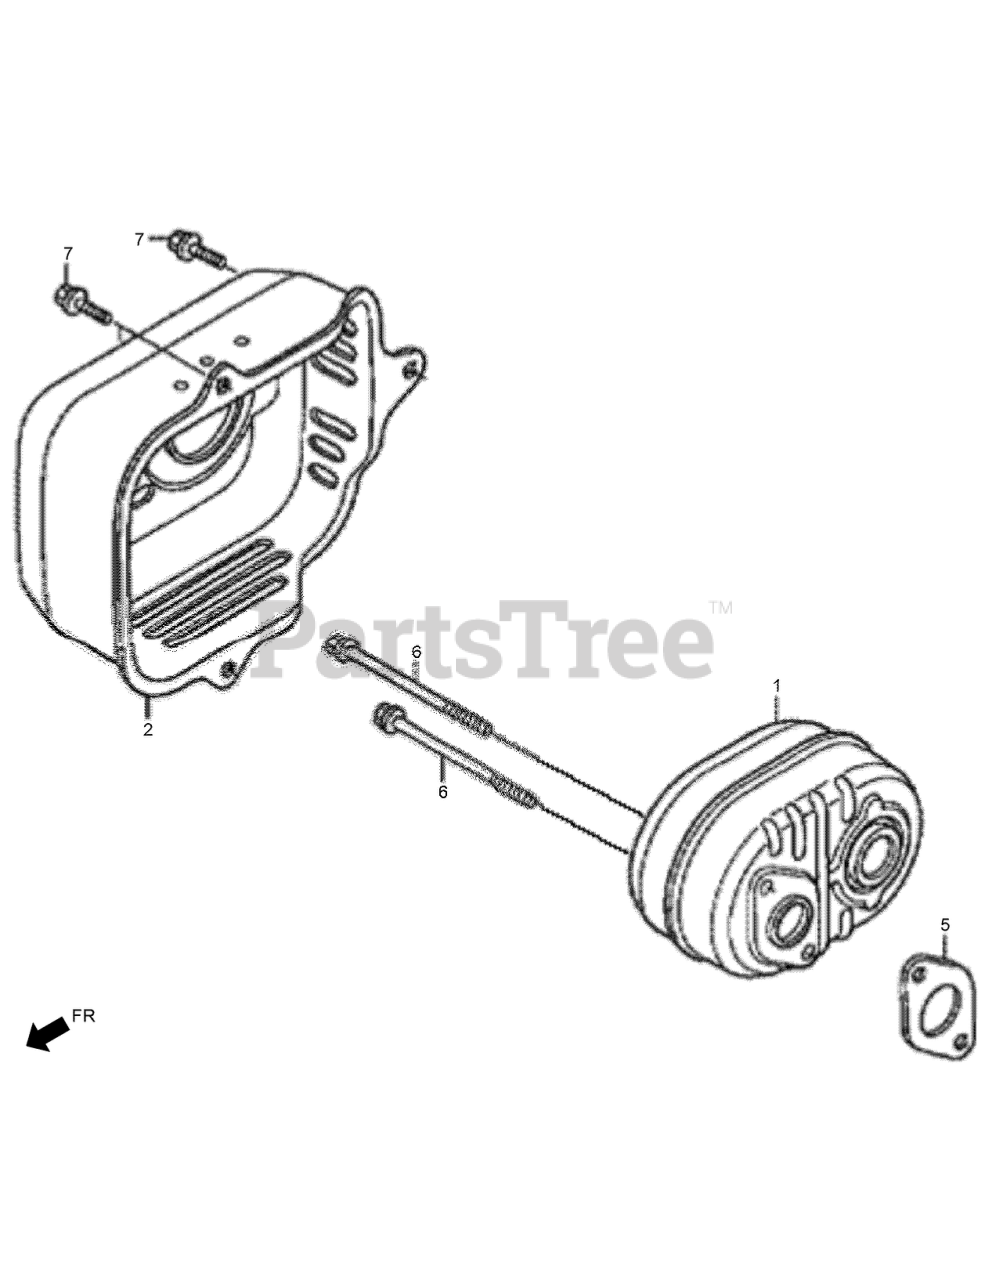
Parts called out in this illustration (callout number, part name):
1	MUFFLER
2	MUFFLER PROTECTOR ASM (to S/N 3176270)
2	MUFFLER PROTECTOR ASM (from S/N 3176271)
2	PROTECTOR-MUFFLER (from S/N 3176271)
5	GASKET-MUFFLER
6	BOLT-FLANGE-6X79
7	BOLT-FLANGE-6X12
